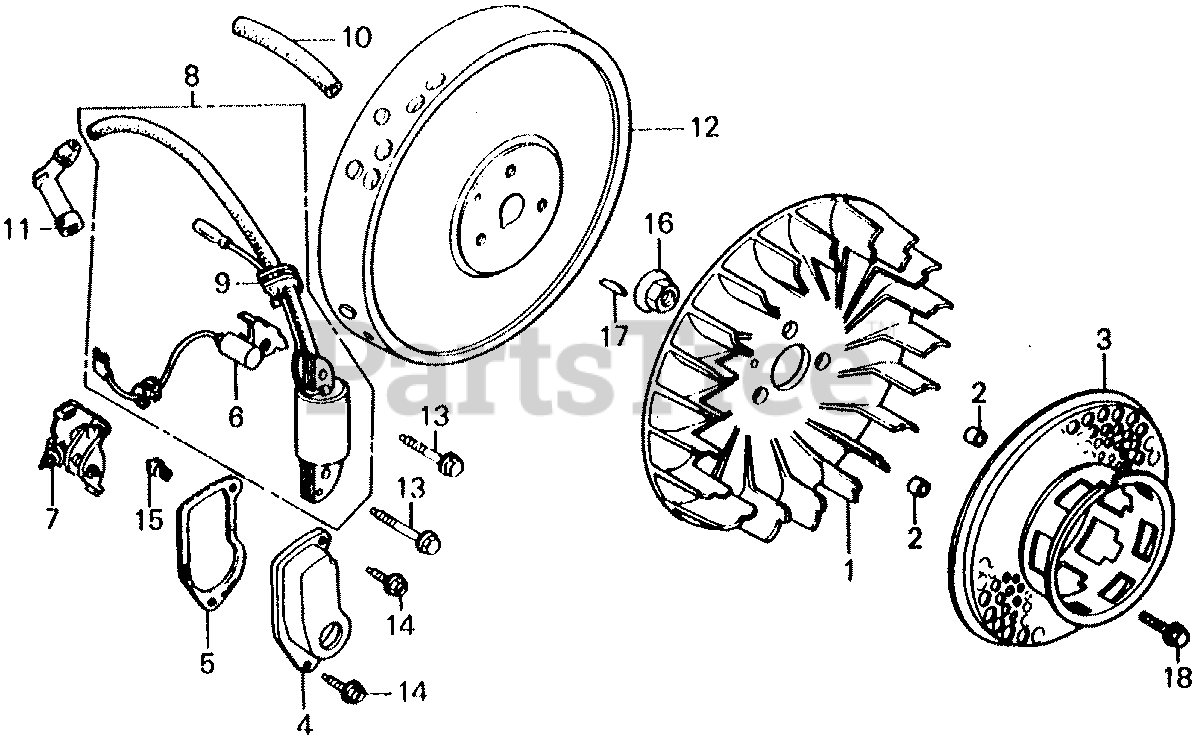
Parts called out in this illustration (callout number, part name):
1	FAN, COOLING
2	COLLAR, FAN
3	PULLEY, STARTER
4	COVER, POINTS
5	GASKET, POINT COVER
6	CONDENSER
7	POINTS ASSY.
8	COIL ASSY., IGNITION
9	GROMMET, WIRE
10	TUBE, IGNITION RUBBER
11	CAP ASSY., NOISE SUPPRESSOR
13	BOLT, FLANGE (6X32)
14	BOLT, FLANGE (5X10)
15	SCREW-WASHER (5X12)
16	NUT, SPECIAL (14MM)
17	KEY, SPECIAL WOODRUFF (25X18)
18	BOLT, FLANGE (6X16)
